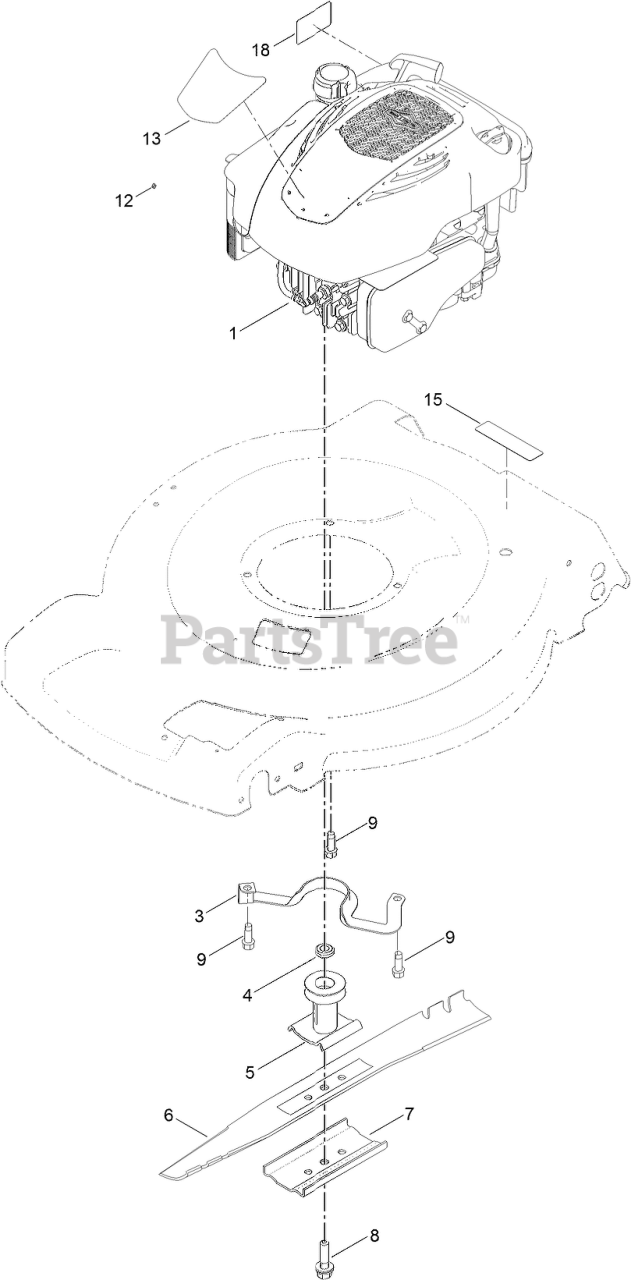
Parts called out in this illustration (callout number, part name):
3	Guide-Belt
4	Spacer-Driver
5	DRIVER-BLADE
6	BLADE-22 INCH
7	SUPPORT-BLADE
8	BOLT-BLADE
9	SCREW-TAPTITE
12	STOP-ROPE
13	DECAL-SHROUD
15	DECAL-ARRESTER, SPARK
18	DECAL-FUEL LEVEL
